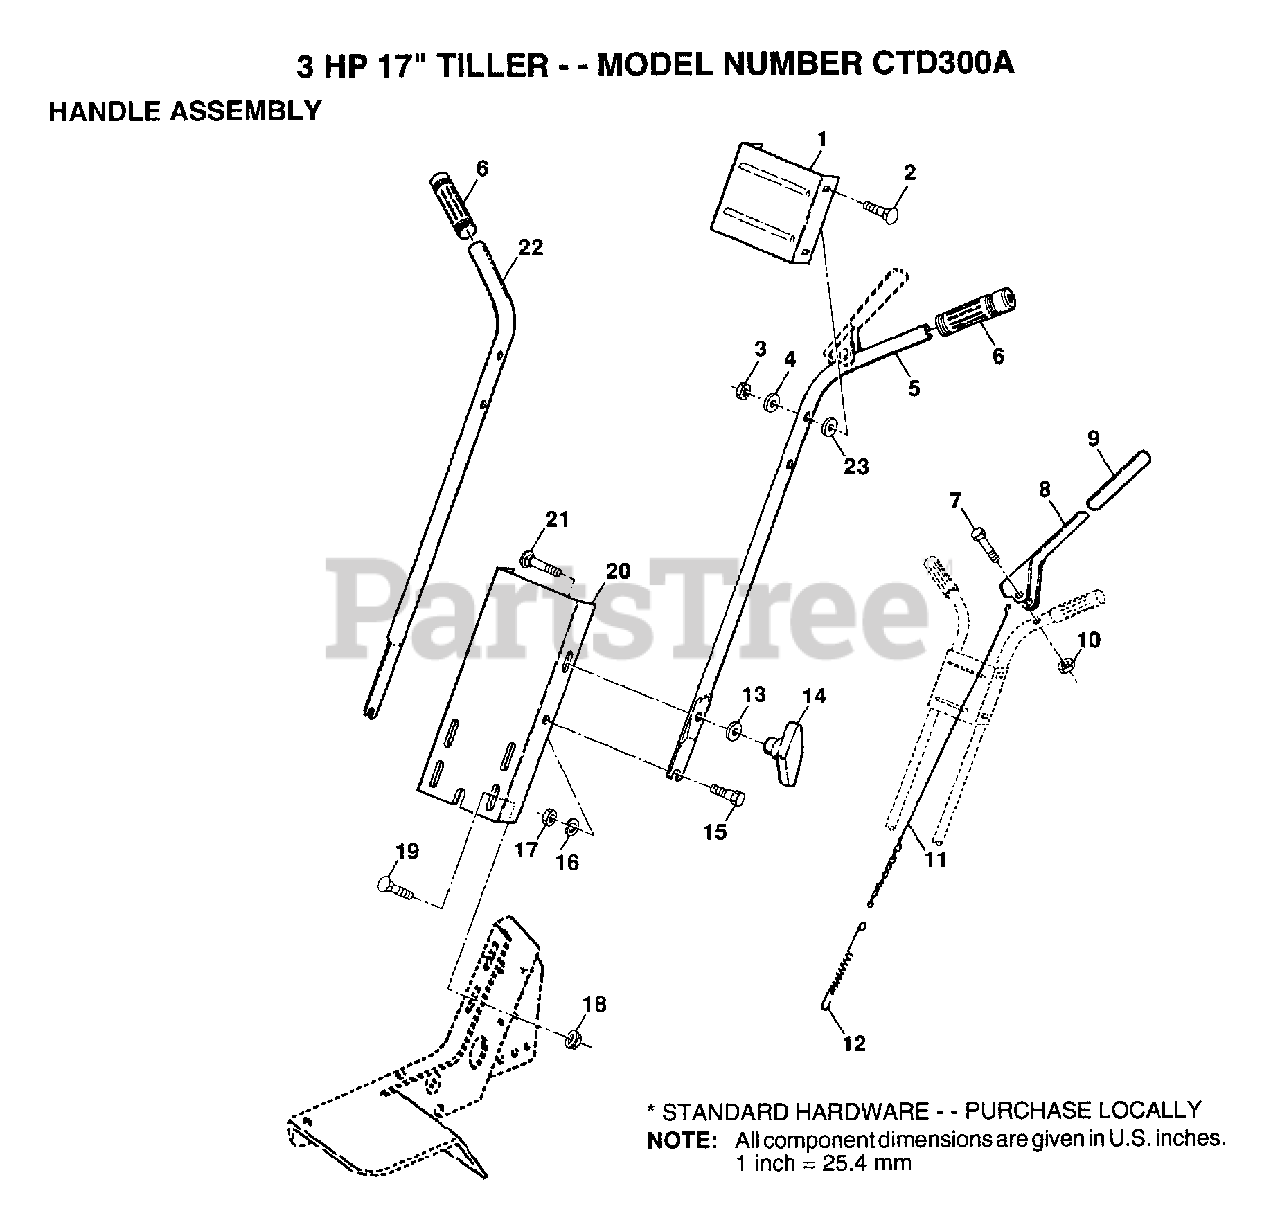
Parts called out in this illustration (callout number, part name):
2	BOLT
4	WASHER
7	BOLT.HEX.5/16-1.5
9	GRIP T
12	SPRING EXT TI
13	WASHER
16	LOCKWASHER
17	NUT.HEX.5/16-18
18	NUT
19	BOLT
21	BOLT
23	WASHER
